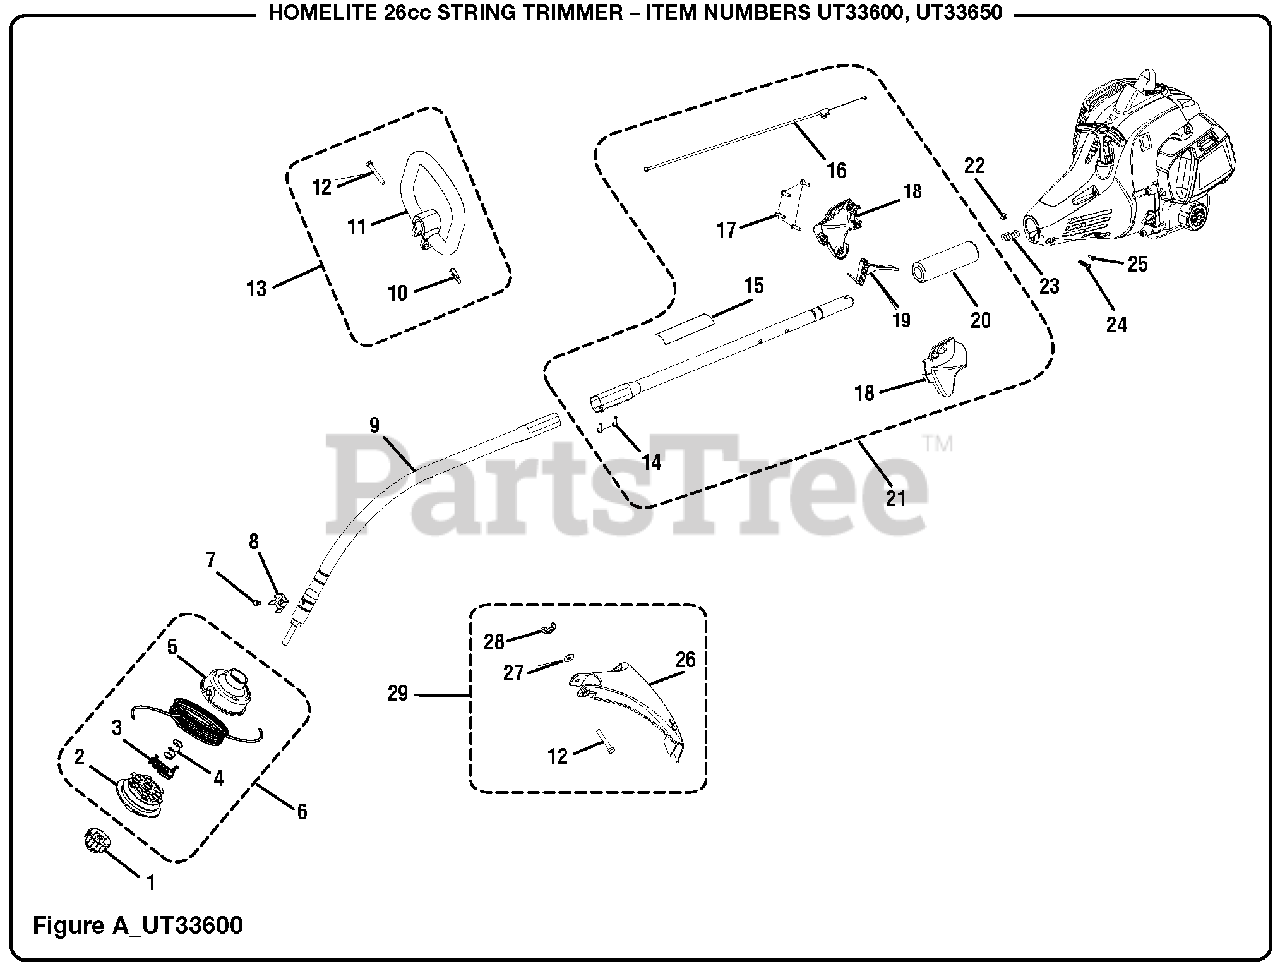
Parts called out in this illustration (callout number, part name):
1	Spool Retainer
3	Spool Cover
4	Compression Spring
5	String Head Housing
6	String Head Assembly
7	Screw (10-32 x 3/8 in., Hex Hd.)
9	Lower Boom Assembly
10	Wing Nut (1/4-20, Plastic)
11	Front Handle
12	Bolt (1/4-20 x 45 mm, Cap Hex Hd.)
13	Front Handle Assembly
14	Screw (M5 x 10 mm, Hex. Soc. Hd.)
15	Icon Warning Label
16	Throttle Cable
17	Screw (M4 x 20 mm, T20 Torx Pan Hd. T.F.)
18	Trigger Handle Assembly
19	Throttle Trigger
20	Foam Grip
21	Boom Assembly
22	Hex Nut (M6)
23	Compression Spring
24	Screw (M6 x 20 mm, T27 Torx Button Hd.)
25	Screw (M4 x 8 mm, T20 Torx Round Hd.)
26	Grass Deflector
28	Wing Nut (1/4-20)
29	Grass Deflector Assembly
